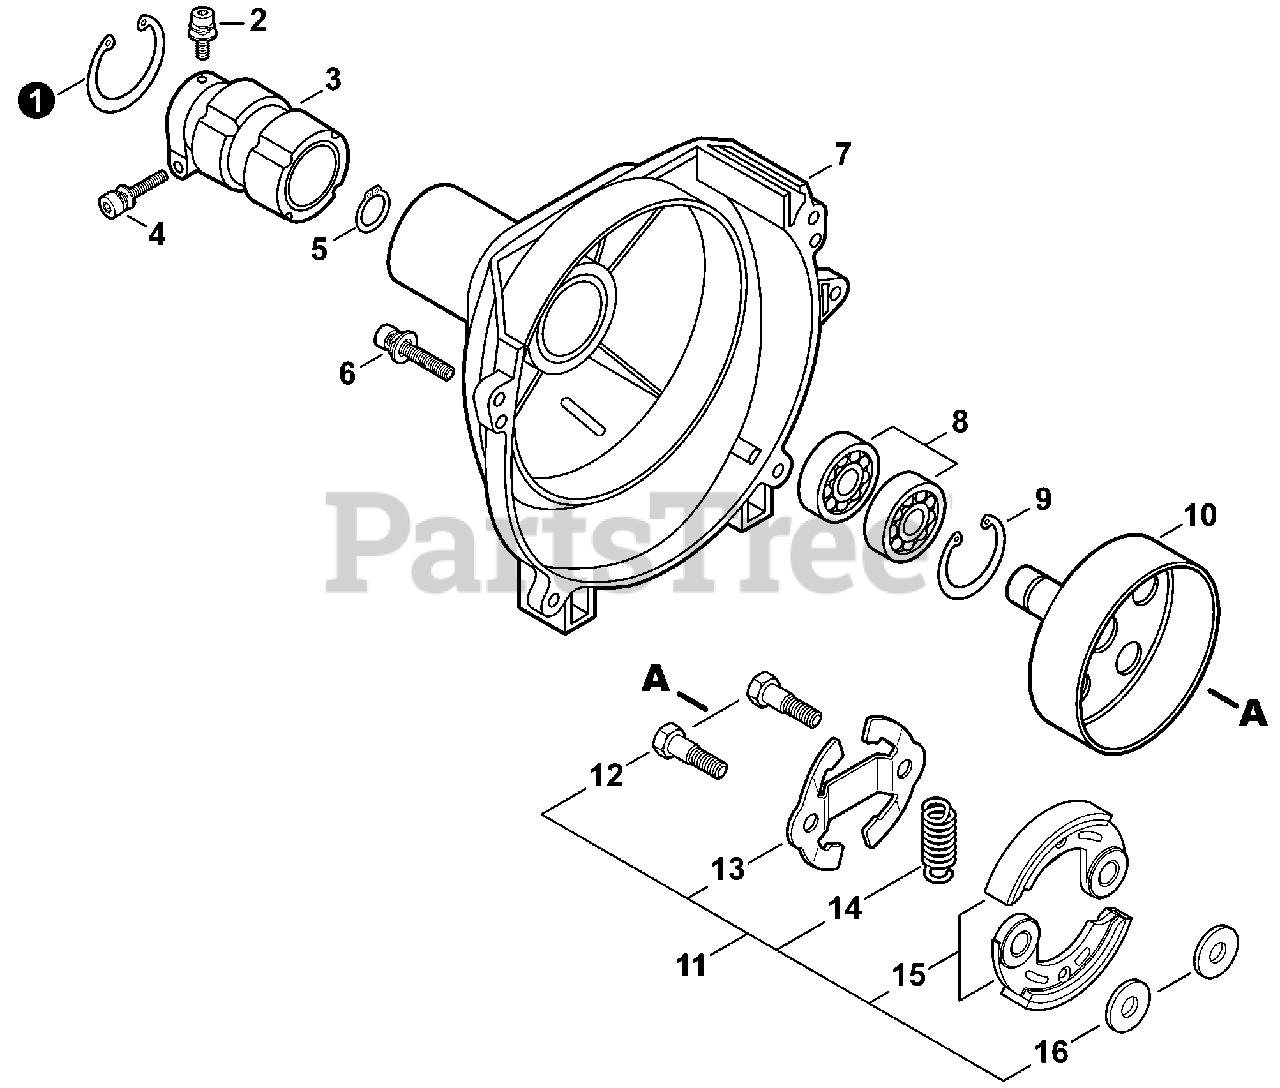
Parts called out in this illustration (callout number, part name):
1	RING, RETAINING Ø45
2	BOLT 5×12
3	CUSHION
4	BOLT 5×28
5	RING, RETAINING - 12
6	BOLT 5×20
7	COVER, FAN
8	BEARING, BALL 6001
9	RING, SNAP 28
10	DRUM, CLUTCH
11	CLUTCH ASSY
12	BOLT, CLUTCH
13	SPRING, FLAT
14	SPRING, TENSION
15	SHOE, CLUTCH
16	WASHER 8.2×17×1.6
